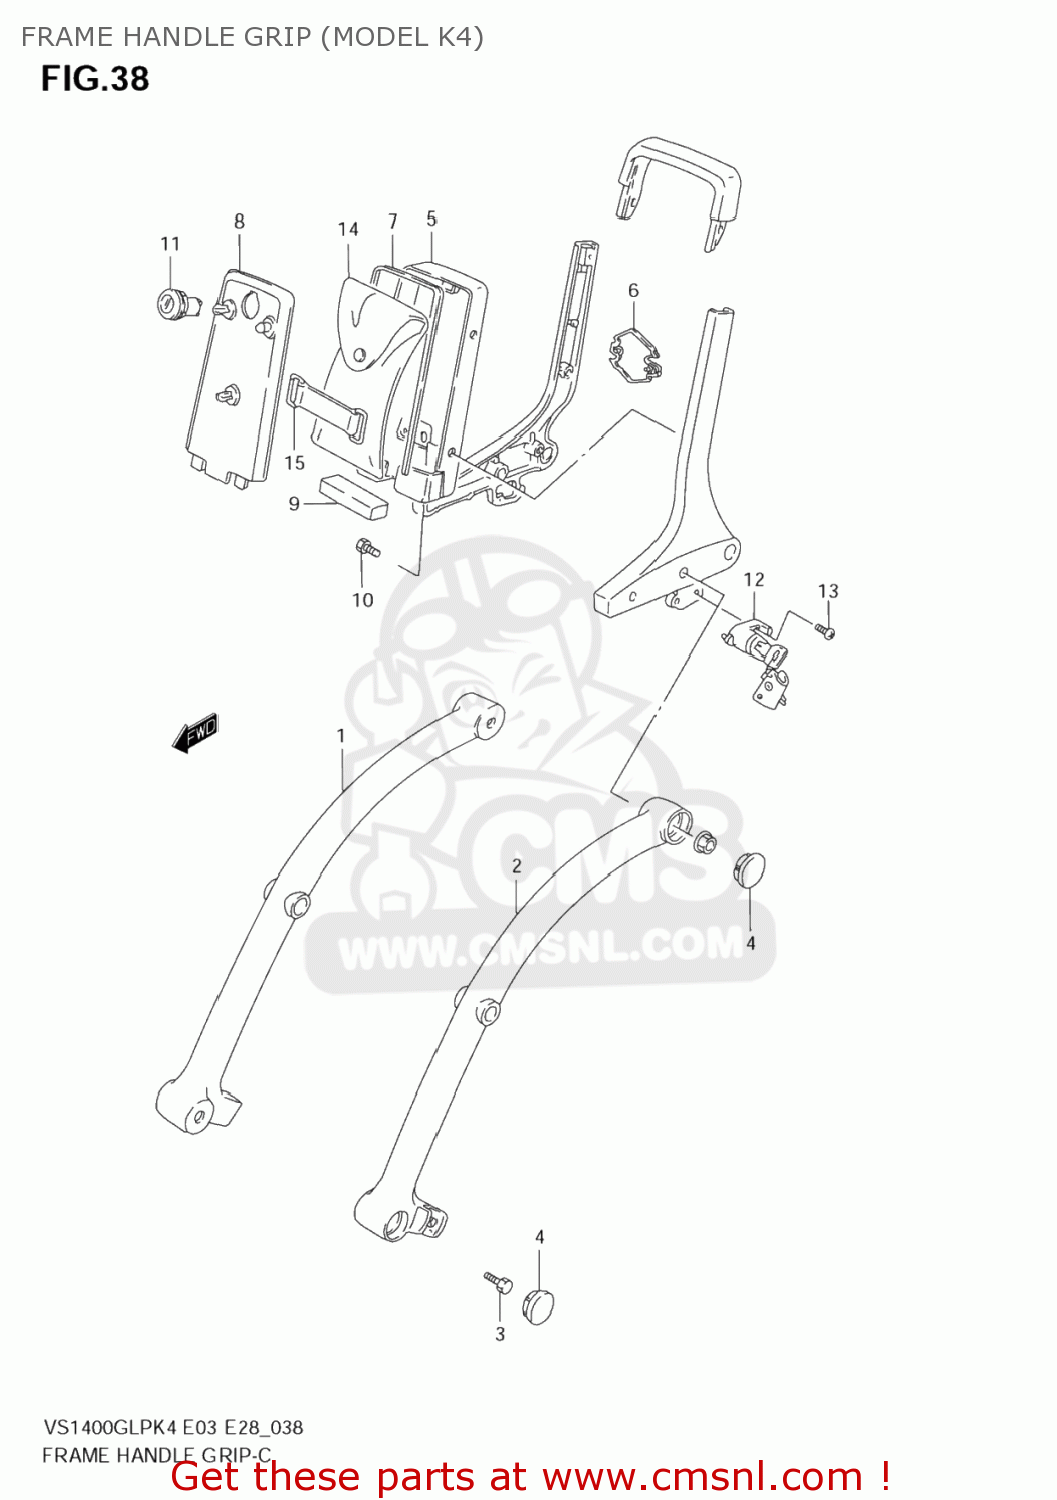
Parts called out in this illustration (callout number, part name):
1	GRIP,FRAME HANDLE,R
2	GRIP,FRAME HANDLE,L
3	BOLT
4	CAP,PIPE CO-RIDER GRIP
5	HOLDER,TOOL RR
6	EMBLEM,TOOL HOLDER RR
7	MOLDING,TOOL HOLDER RR
8	HOLDER,TOOL FR
9	CUSHION,TOOL BACK
10	BOLT
11	LOCK SET,TOOL HOLDER
12	LOCK SET,HELMET
13	SCREW
14	TOOL ASSY
15	BAND
